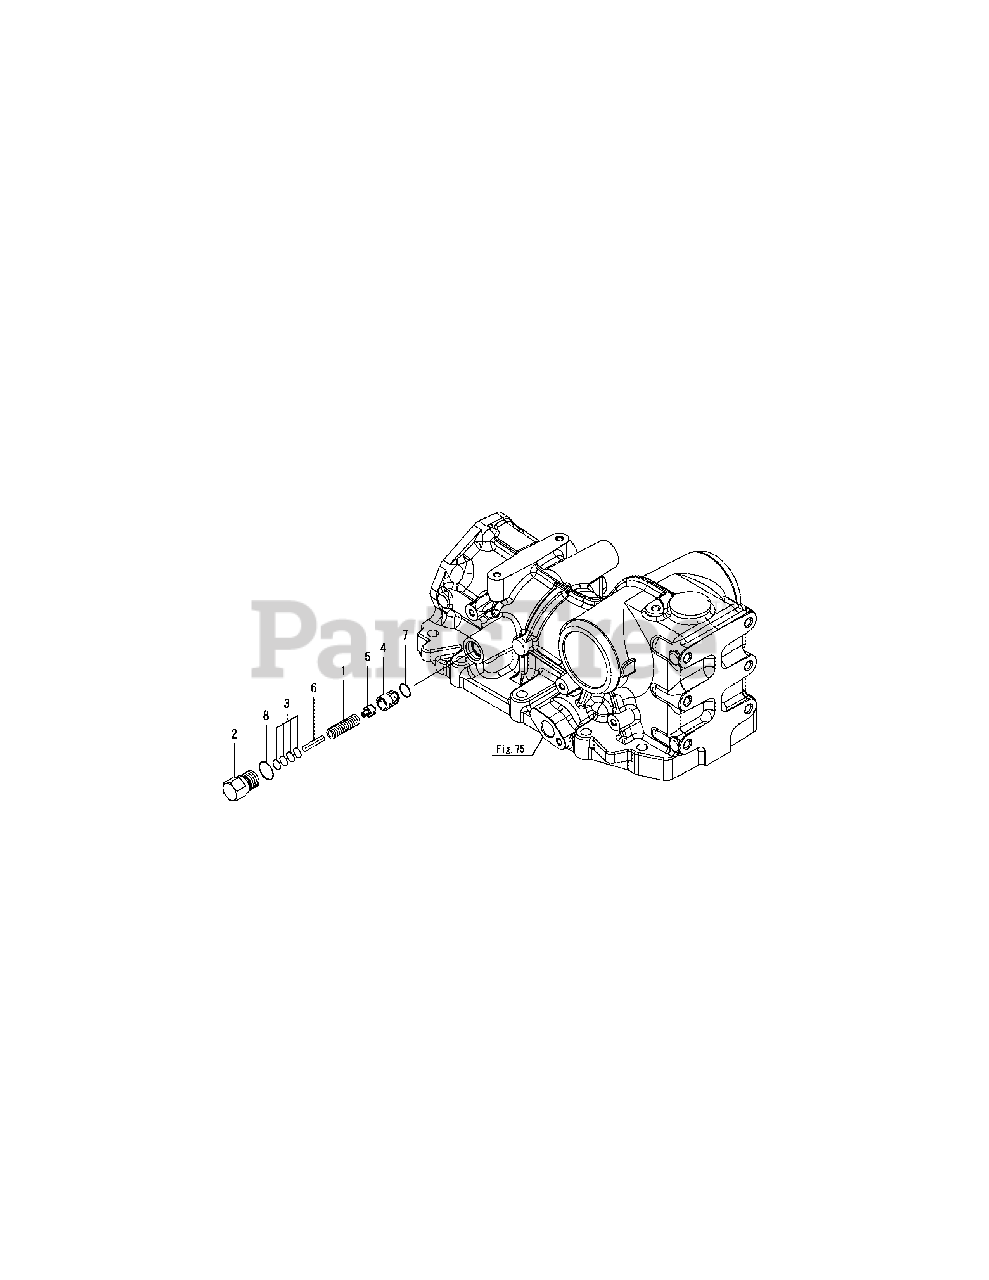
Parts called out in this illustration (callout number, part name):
2	PLUG, SAFETY VALVE
4	SEAT, SAFETY VALVE
5	POPPET, SAFETY VALVE
6	SPRING PIN 6X30
7	O-RING 1B P-12.0
8	O-RING 1B P-18.0
